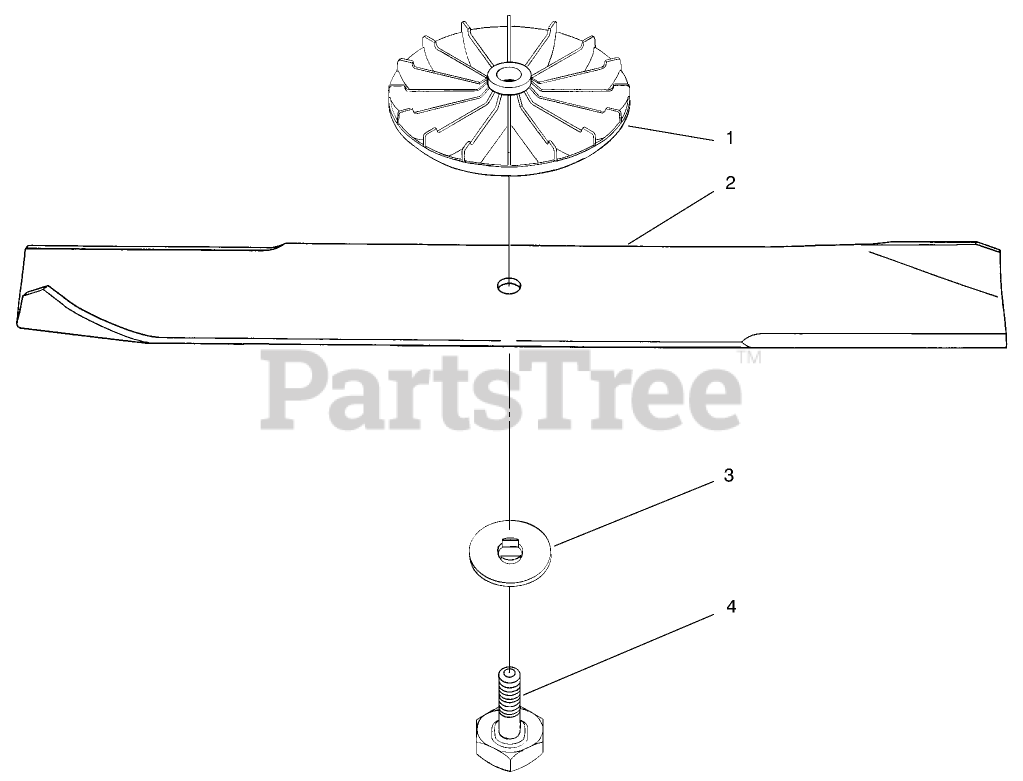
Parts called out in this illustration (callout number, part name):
1	RETAINER - BLADE
2	BLADE
3	CARRIER - BLADE
4	SCREW - COVERED BLADE
